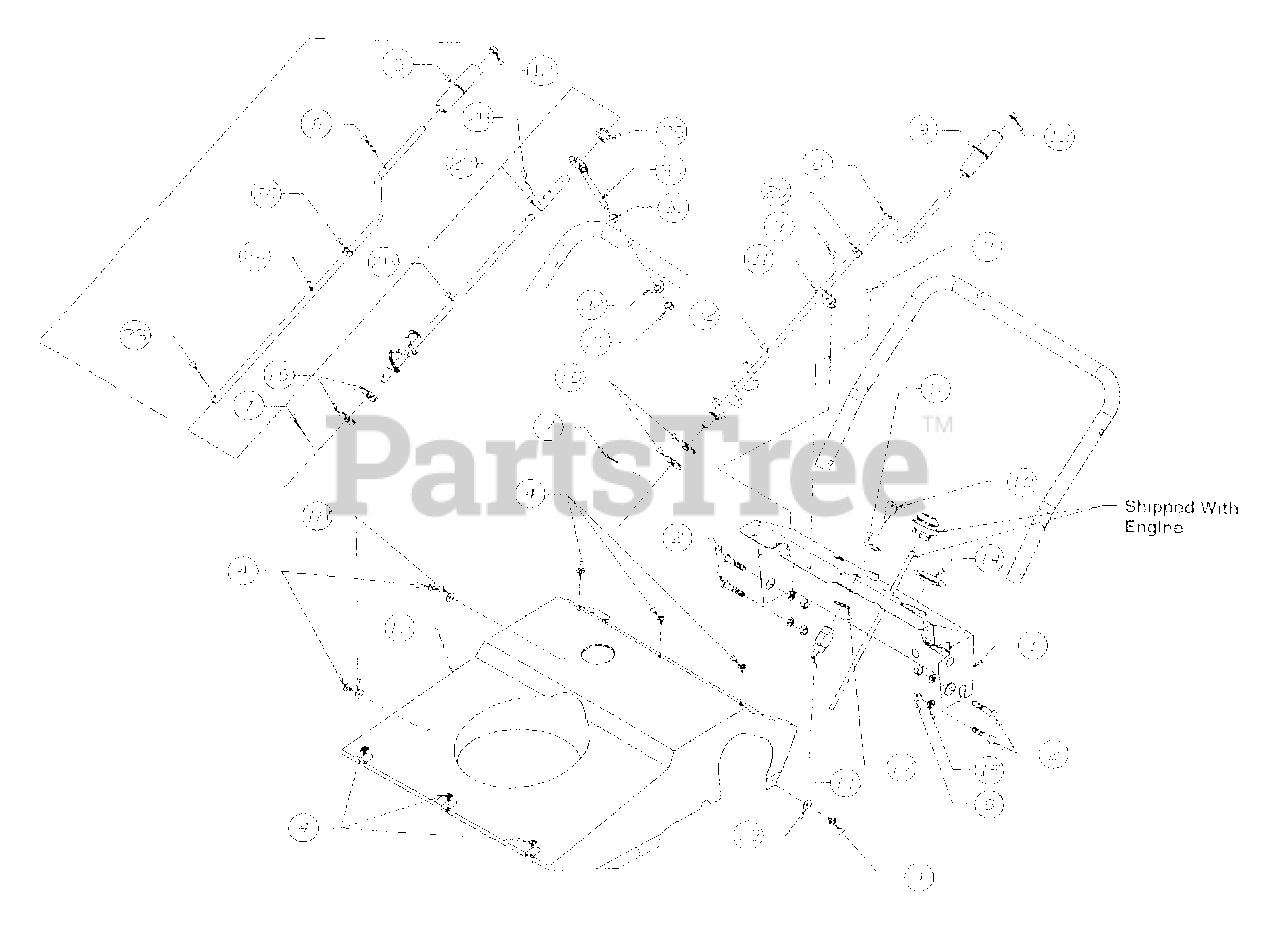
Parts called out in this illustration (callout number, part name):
3	Hex Tap Screw
4	Hex Tap Screw
9	Chute Crank Knob
10	Key-Ignition
11	Switch-Key
14	Plug
15	Lock Washer
17	Internal Lock Washer
20	Bushing
21	Bracket, Chute Crank
22	Crank Assembly, Chute
23	Cotter Pin
29	Grommet - Rubber
30	Eyebolt - Chute Crank
31	Nut - Hex
32	Washer-Saddle
